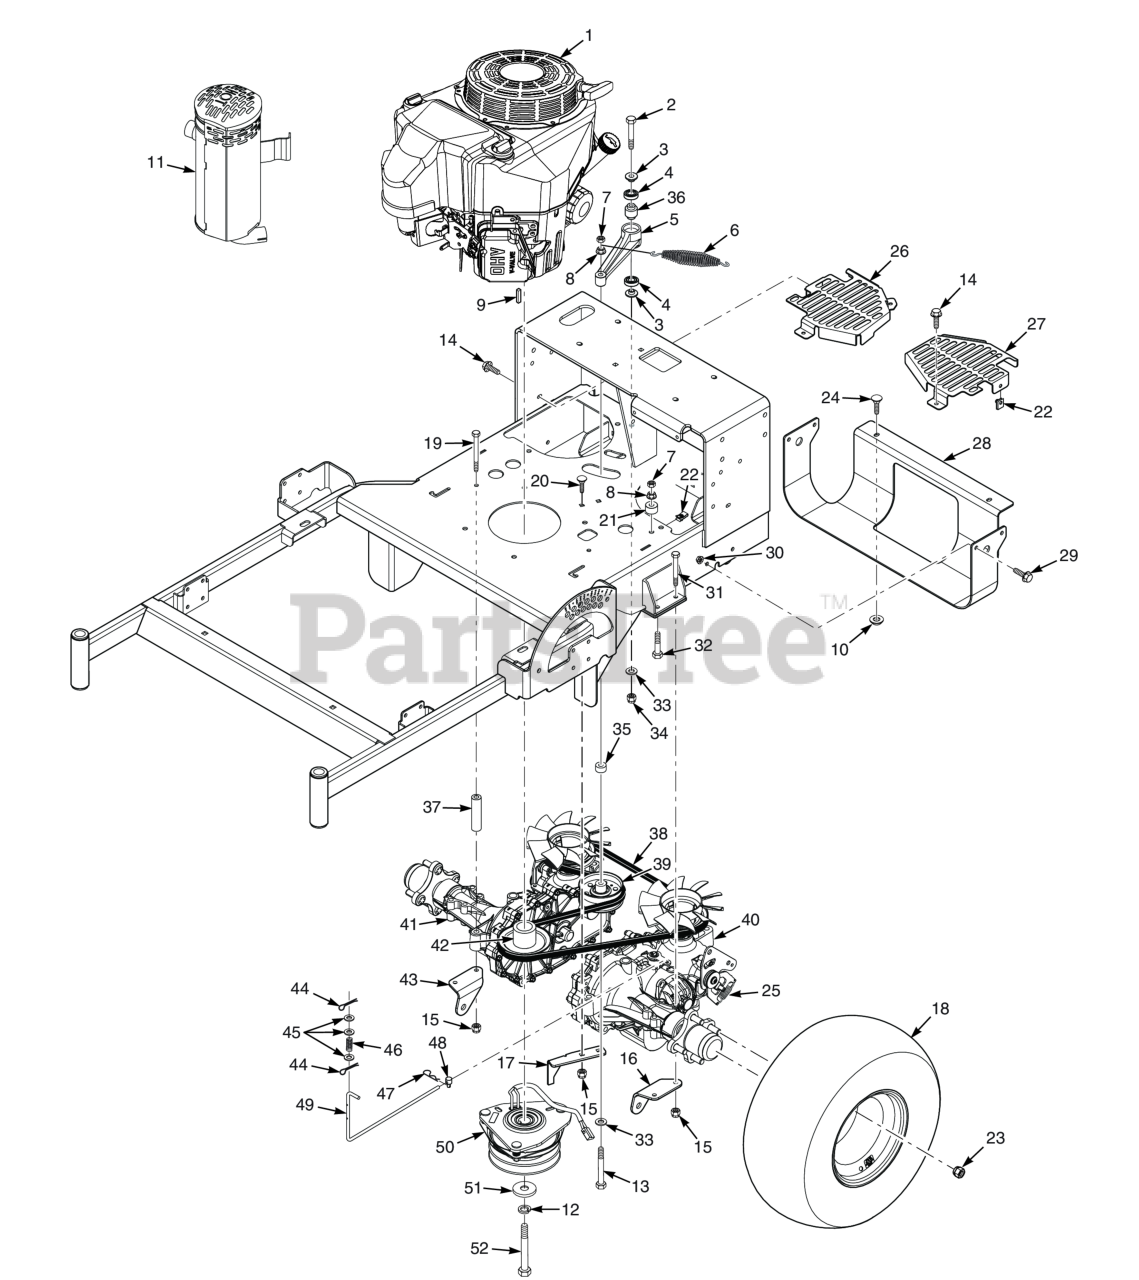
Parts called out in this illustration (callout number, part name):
1	Engine, Kawasaki 14FS (FS481V)
2	Bolt, Hex Head 3/8-16 x 3" - 52"
3	Spacer, Controls
4	BEARINGS, BALL, NEUTRAL RETURN
5	Trans. Idler Arm Assy. (Includes 24, 79)
6	Spring, Transmission Idler
7	Bolt, Hex Head 3/8-16 x 1" Ser. Flg.
8	NUT, 3/8-16 SERRATED FLANGE HEX HEAD
9	KEY, 1/4 X 1/4 X 2-1/2"
10	Nut, Push-On 5/16-18
11	Muffler, Kawasaki (FS481, FS541, FS600)
12	Lockwasher, 7/16� Spring
13	Capscrew, Hex Head 3/8-16 x 3-3/4"
14	Bolt, Serrated Flange Hex Head 1/4 x 20 x 3/4"
15	HEX NUT, ELASTIC STOP LOCK, 5/16-18
16	Pusharm Mount Bracket, LH
17	Bracket, Anti-Rotation
18	Wheel Assembly 18 x 6.5-8 (36" Only)
19	Bolt, Hex Head 5/16-18 x 6-1/2"
20	Bolt, Carriage 5/16-18x1" (large frame units only)
21	SPACER, J PULL ROD
22	Bolt, Hex Head 3/8-16 x 1"
23	Wheel Nut, 1/2-20 x 13/16
24	Bolt, 5/16-18 x .75 RHSN Carriage
25	Spring, RTN
26	Fan Cover, RH
27	Fan Cover, LH
28	Skid Plate
29	Capscrew, 5/16-18 x .75 Serrated Flange Hex Head
30	Nut, Serrated Flange 5/16-18 (Right Front Engine Mounting, Briggs and Kohler Only)
31	Bolt, Hex Head 5/16-18 x 3.00"
32	Bolt, Hex Head 3/8-16 x 2-1/2" 1.5 Thread Grd.8
33	Flatwasher, 3/8 (.391 x .938 x .105 HD) Grade 8
34	HEX NUT, ELASTIC STOP LOCK, 3/8-16
35	Spacer, Idler Pulley - SFZ61
36	Spacer, Bearing
37	Spacer, Axle
38	Belt, Transmission Drive
39	Pulley, 3-1/2" Dia.
40	Transaxle Assy., (ZH-GMCC-SLUB-1MTX)
41	Transaxle Assy., (ZH-KMCC-3LUC-1MTX)
42	Pulley, 4-1/2" Dia. - 1" Bore
43	Pusharm Mount Bracket, RH
44	COTTER PIN, 3/32 X 1"
45	Flatwasher, 1/4" (.312 x .750 x .065")
46	Spring, Dump Valve Link
47	Pin, Rue Cotter 3/8" Diameter
48	Joint, Swivel
49	Link, Dump Valve
50	Electric Clutch Assembly
51	Flatwasher, 7/16-.469 x 1.75 x .25 (48, 52)
52	Bolt, Hex Head 7/16-20 x 3" w/t Patch
